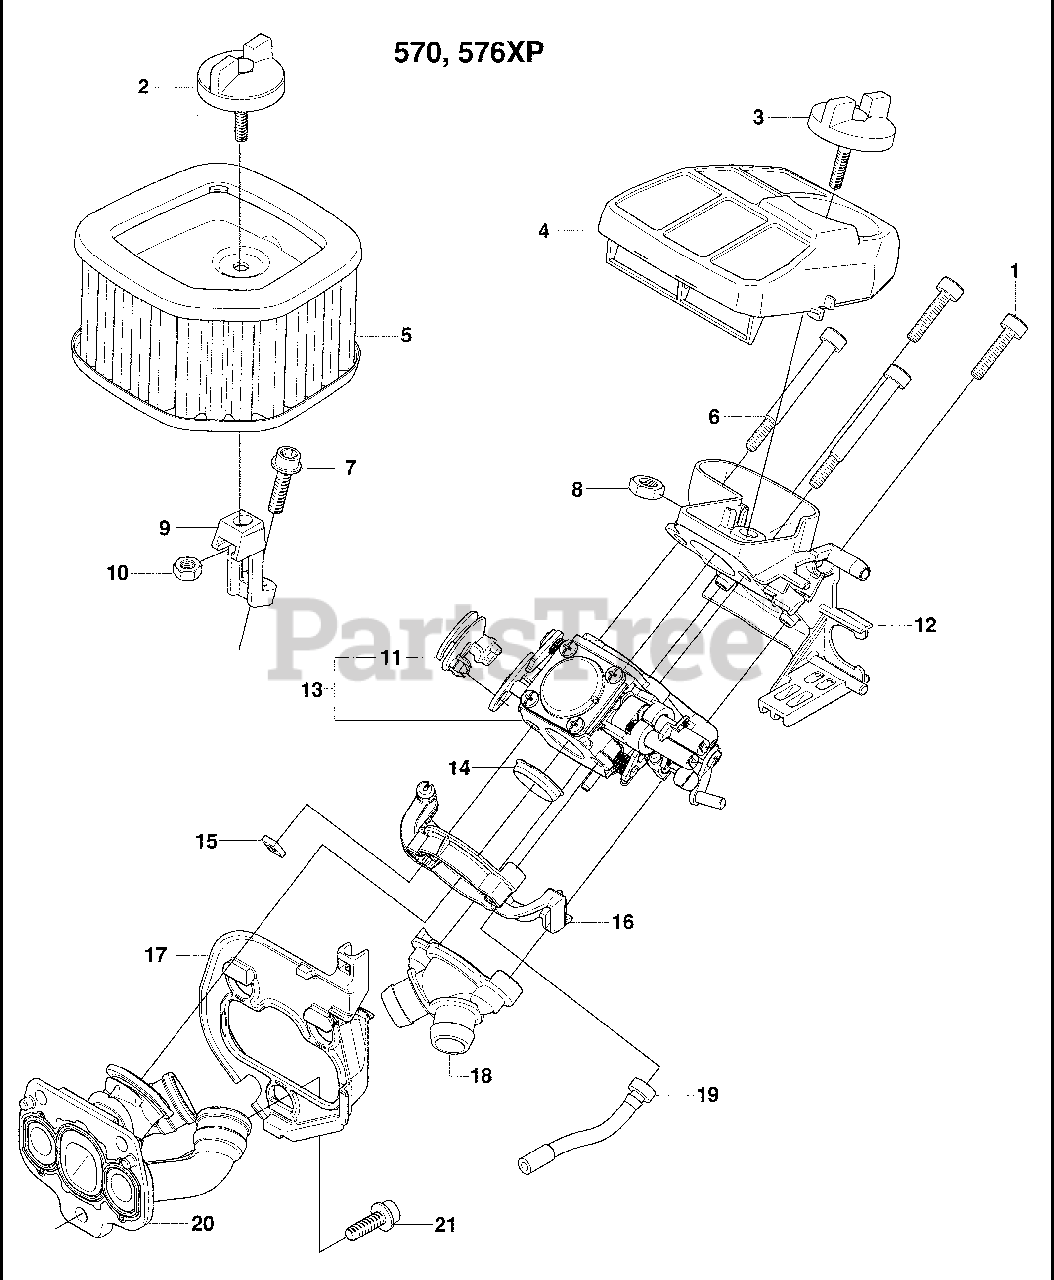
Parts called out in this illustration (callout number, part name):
4	Air Filter
5	Air Filter
5	Air Filter, Winter
5	Air Filter, HD 44
6	Screw, 4 X 46
8	Hex Nut, M5 X .80 DIN
10	Hex Nut, M5 X .80 DIN
12	Filter Holder
13	Carburetor
21	Screw, M5 X 16
